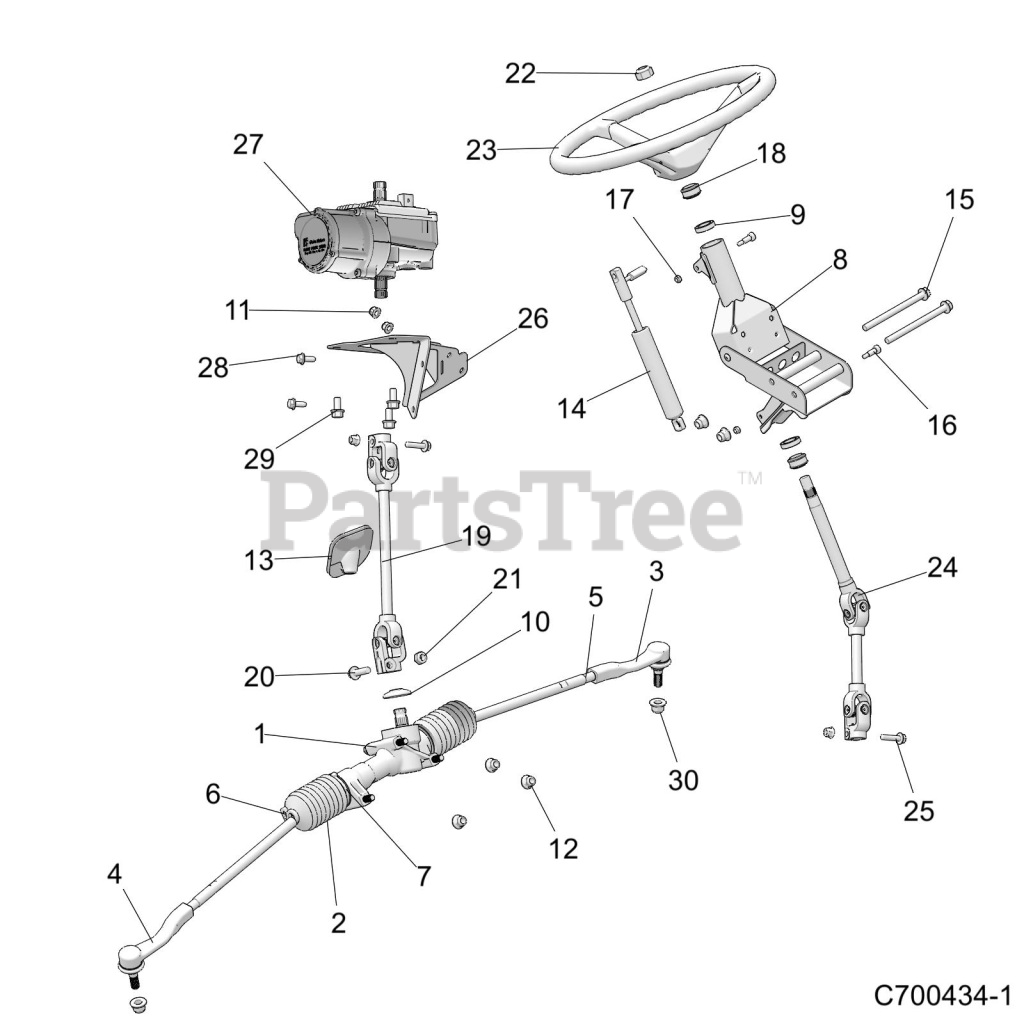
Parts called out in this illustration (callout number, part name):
1	ASM-GEAR BOX,STEERING
2	BOOT-DRIVER SIDE,RACK
3	D.S. OUTER TIE ROD
4	P.S. OUTER TIE ROD
5	NUT, JAM
6	CLAMP, SMALL
7	CLAMP, LARGE
8	ASM,TILT,STEERING,RVTD,M10.BLK
9	BEARING-STEERING
10	COVER-DUST,STEERING
11	NUT-M8X1.25,FLG,NYLOC-OLIVE D
12	NUT-M10X1.25,FLG,NYLOC-OLIVE D
13	GROMMET-STEERING
14	ASM-SHOCK,OIL LOCKING,MACH
15	BOLT-M10X1.25X130,HXFLG-OLIVED
16	BOLT-SHOULDER,M8-15,M6X1.0-BLK
17	NUT,NYLOK(10)
18	BUSHING-STEERING
19	SHAFT, STEERING, LOWER, W/JOINT, EPAS
20	SCR-M10X1.50X35 HX/FL
21	NUT-NY INS,M10X1.5,HEX,ZINC,YW
22	NUT-HEX-M16X2, 8 ZC NYL
23	WHEEL-STEERING,15"
24	SHAFT, STEERING, UPPER
26	WELD-EPAS,MNT,BLK
27	ASM-POWER STEERING,RANGER
28	BOLT-M8X1.25X20,HXFLG,TAP/R-OD
29	BOLT-M10X1.25X20,HXFLG-OLV D
30	NUT-M12X1.5,FLG,NYLOC-OLIVE D
